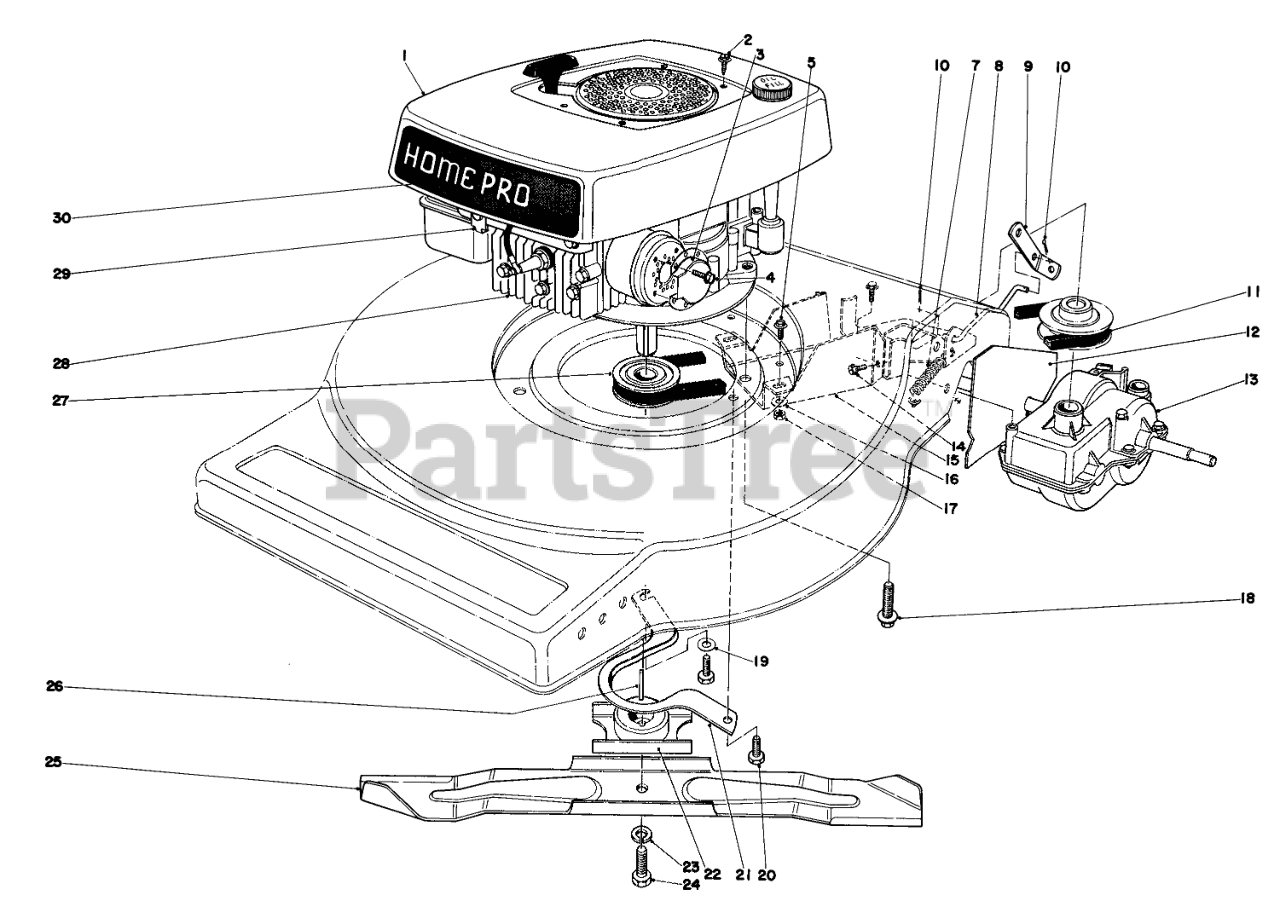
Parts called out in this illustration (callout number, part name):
1	Shroud
2	8X1/2 SELF TAP SCREW
3	Deflector
4	SCREW W/ENGINE
5	SCREW-HWH
7	IDLER SPRING
8	Link Clutch
9	Bracket Clutch Pivot
10	PIN-COTTER
11	V-BELT
12	GRASS SHIELD
13	Gear Case Assembly Complete
14	SCREW-HWHTF
15	COVER-BELT
16	WASHER-FLAT
17	Nut
18	SCREW-HWHTF
19	WASHER-FLAT
20	SCREW THD 1/4 20 5/8
21	Belt Guide
22	Blade Retailer
23	WASHER-LOCK
24	SPECIAL SCREW
25	Blade
26	KEY-SQUARE
27	DRIVER PULLEY
28	Engine
29	Bracket Control
30	Decal Shroud
